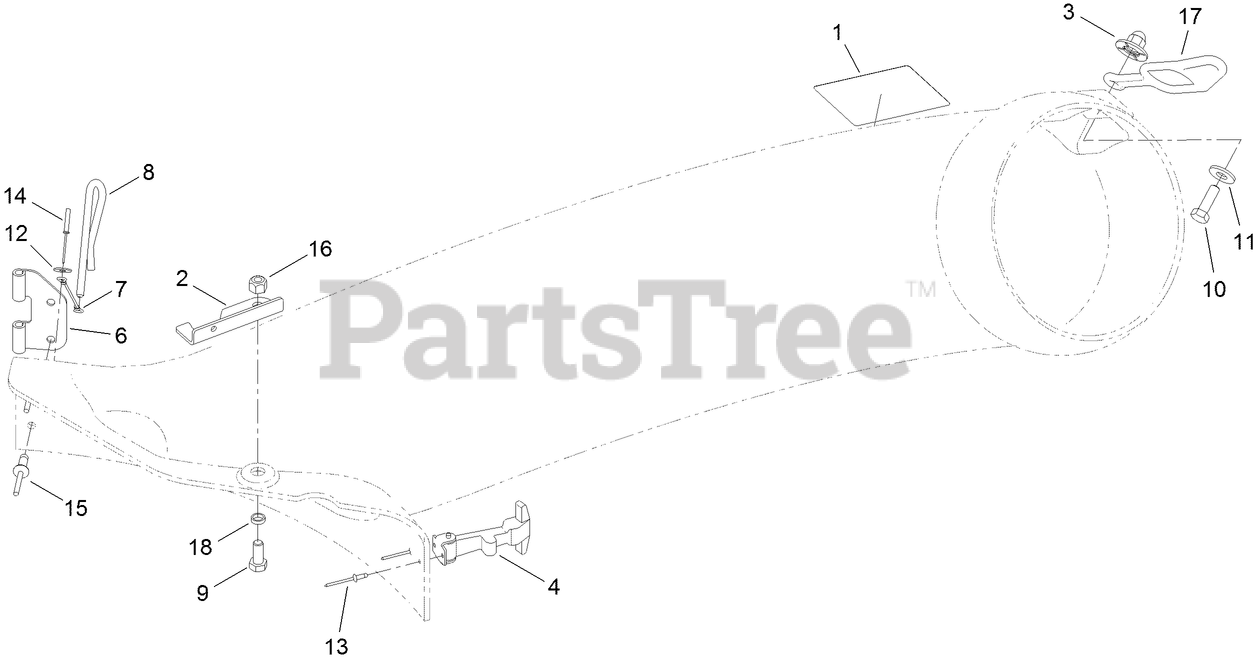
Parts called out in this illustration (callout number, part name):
1	DECAL-DANGER
3	NUT-IMPELLER
4	HANDLE ASM
6	BRACKET-CHUTE MOUNTING
7	LANYARD
8	PIN-LOCKING, CHUTE
9	SCREW-HH
10	SCREW-HH
11	WASHER-FLAT
12	WASHER-PLAIN
13	RIVET-POP
14	RIVET-BLIND
15	RIVET-BLIND
16	NUT-LOCK, NI
17	RETAINER-DUCT
18	BUSHING
